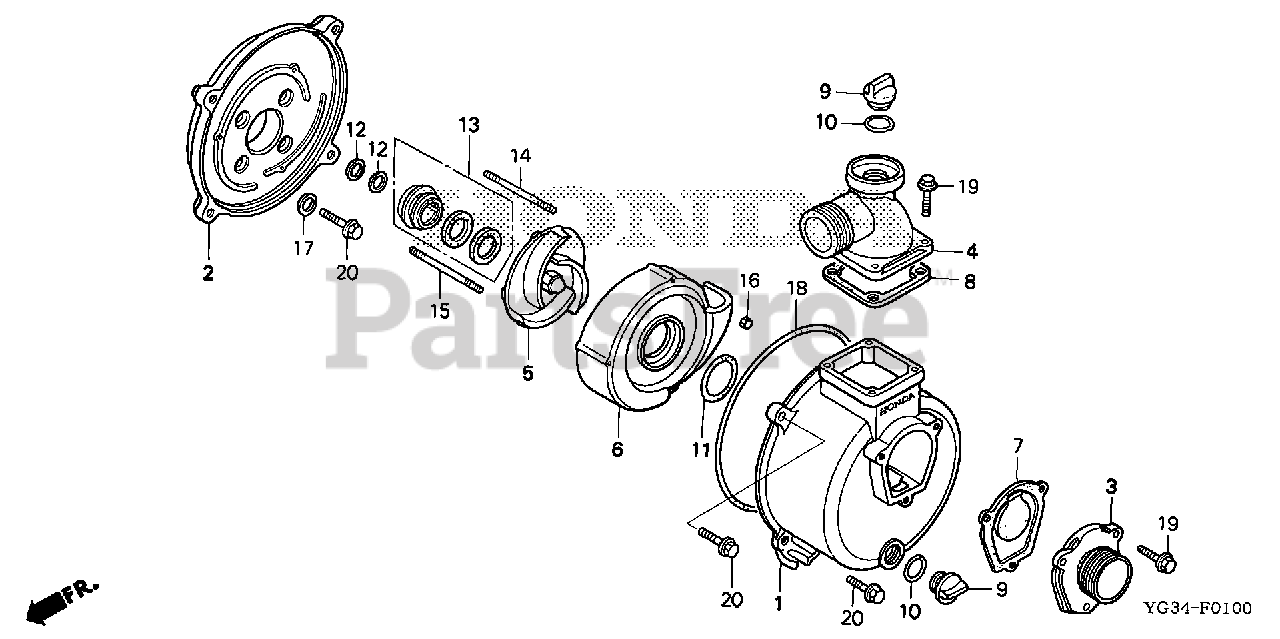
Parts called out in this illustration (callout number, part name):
2	COVER, CASING
3	INLET (NPTF)
4	OUTLET
6	CASE, VOLUTE
7	VALVE, IN.
8	GASKET, OUTLET
9	CAP, FILLER
10	O-RING (23.7X3.5)
11	O-RING (49X5.7)
12	SHIM, ADJUSTER
13	SEAL ASSY., MECHANICAL WATER
14	BOLT, STUD (6X50) (CT200)
15	BOLT, STUD (6X50) (CT200)
16	NUT, CAP (6MM)
17	WASHER, SEALING (8MM)
18	O-RING (217.5X3.5)
19	BOLT, FLANGE (8X25)
20	BOLT, FLANGE (8X28)
